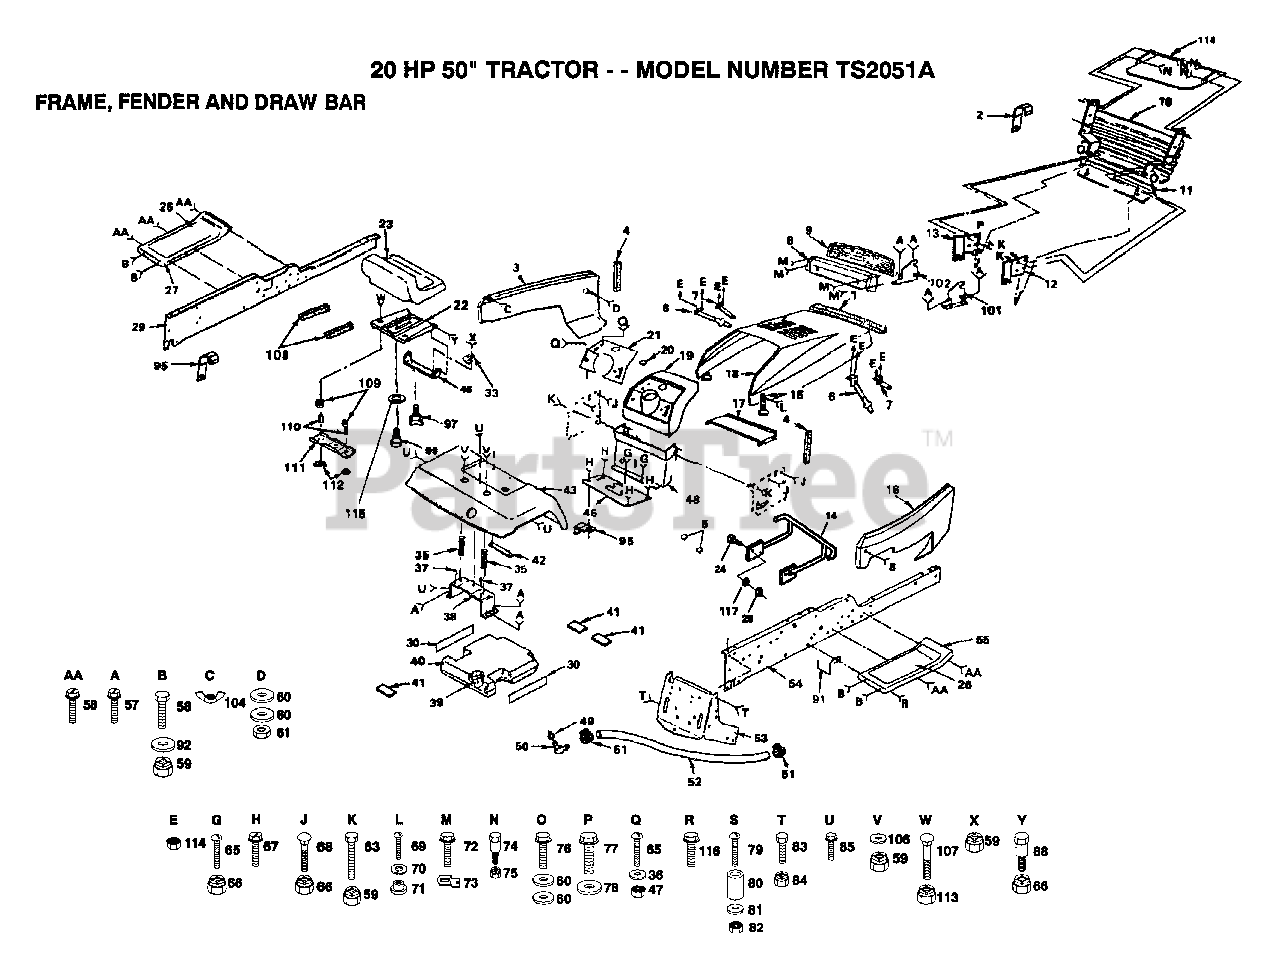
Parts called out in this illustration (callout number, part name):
1	FOAM STRIP T
4	FOAM STRIP T
5	CAP SPRING
9	LENS LT
12	SUPPORT RH YTH
13	SUPPORT LH YTH
14	BUMPER ASSY.
15	HOOD LATCH T
16	"PANEL,SIDE RH "
20	PLUG-DASH T
24	BOLT
26	FOOTREST PAD
30	PAD IDLER TI
33	CLIP T
35	SPRING COMPRESSIO
36	WASHER
37	NUT-PUSH YT
41	PAD-SPACER LT
43	FENDER
46	SADDLE.6SP.GT
48	DASH ASSEMBLY
49	BUSHING OUTLET T
51	HOSE CLAMP
57	SCREW
60	WASHER PM
63	BOLT
65	SCREW
67	SCREW
68	BOLT
69	SCREW
70	LOCKWASHER
71	WELDNUT
73	"""J"" FASTENER LT"
76	SCREW HEX CRT
77	SCREW
78	WASHER
79	SCREW
80	SPACER LT
81	WASHER
83	BOLT
84	NUT GTV
85	SCREW LT
91	BELT RETAINER GT
92	WASHER
97	"KNOB 1/2"" YT"
99	"BOLT,SHOULDER"
101	SUPPORT RH YTH
102	SUPPORT LH YTH
106	WASHER
108	STRIP FORM
109	SPRING COMPRESSED
110	SPACER SPLIT
111	BRKT SWITCH
112	BUSHING
114	NUT
115	WASHER
116	SCREW GTV
117	WASHER
118	"SHIELD,HEAT"
